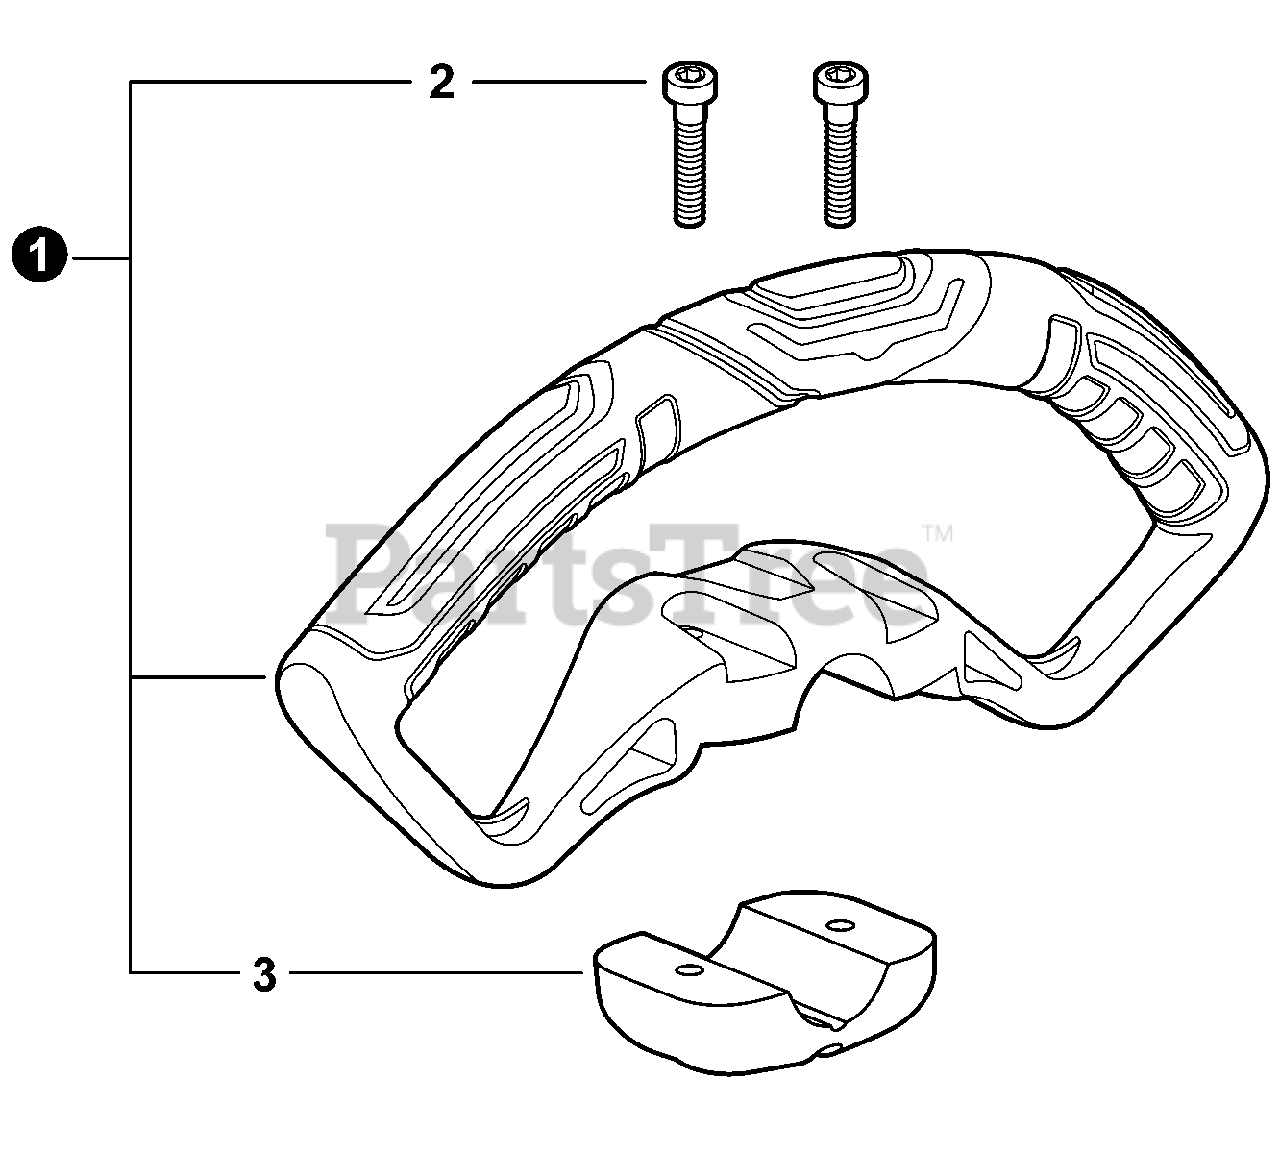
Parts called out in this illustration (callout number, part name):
1	HANDLE ASSY, SUPPORT
2	BOLT, TORX 5x30
3	BRACKET, HANDLE
